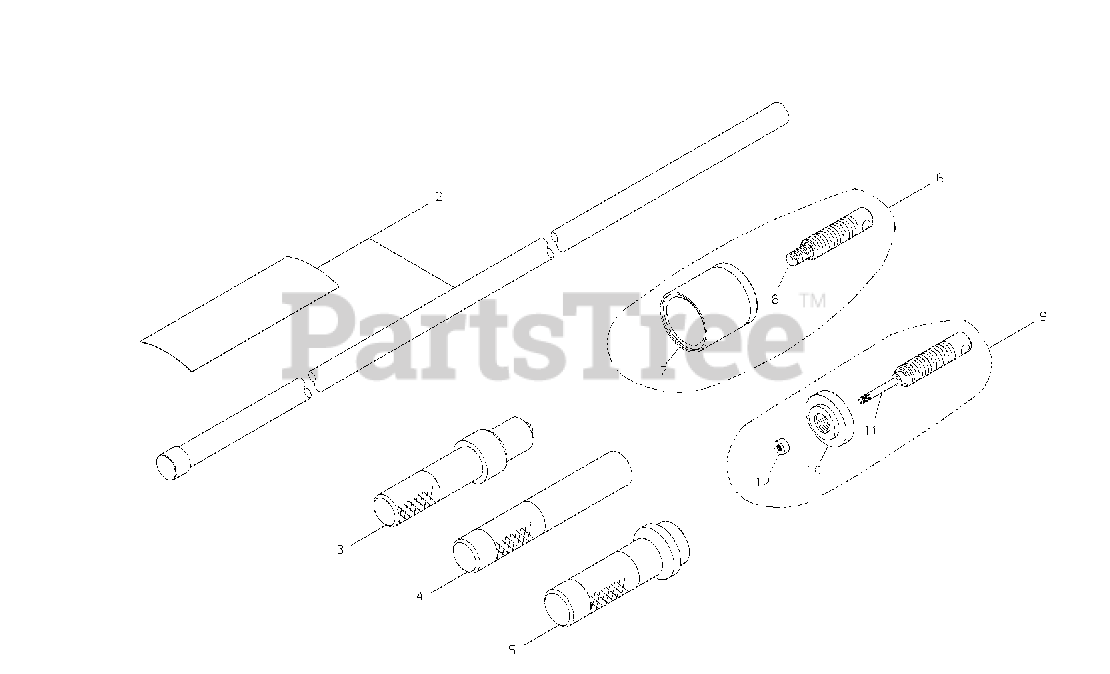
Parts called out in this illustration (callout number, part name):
2	ROD BUSHING ASSY
3	BEARING DRIVER (6000 DDU)
5	BEARING DRIVER (6202)
6	STARTER PAWL ASSY
7	HOLDER
8	PULLER BOLT
9	STARTER PAWL ASSY
10	HOLDER
